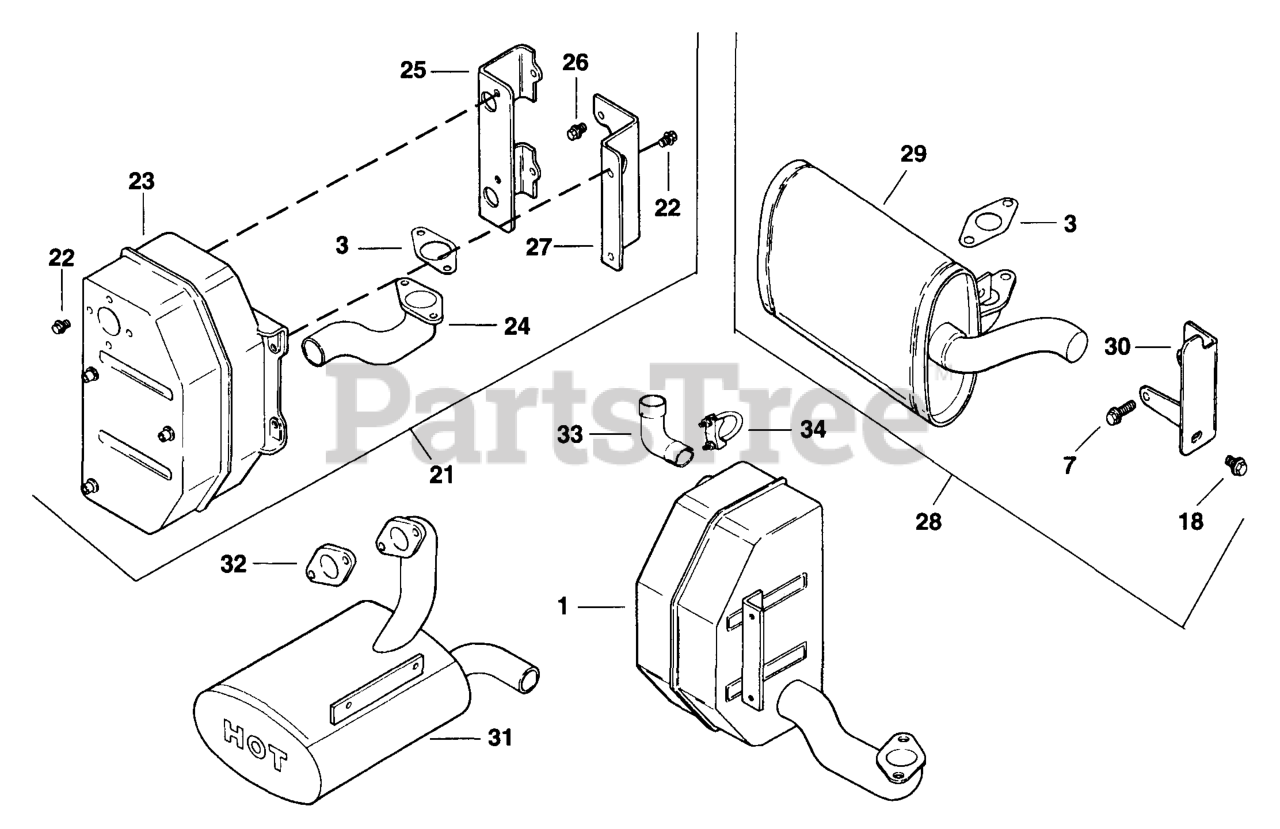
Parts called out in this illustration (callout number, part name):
3	GASKET, EXHAUST MANIFOLD
7	SCREW - USE M-645025
21	KIT, MUFFLER - DISCONTINUED
22	Screw, hex. flange M6x1.0x16
24	PIPE, INLET
25	BRACKET, MUFFLER - DISC.
26	Screw, hex. flange M6x1.0x25
27	BRACKET, MUFFLER - DISCONTINUED
